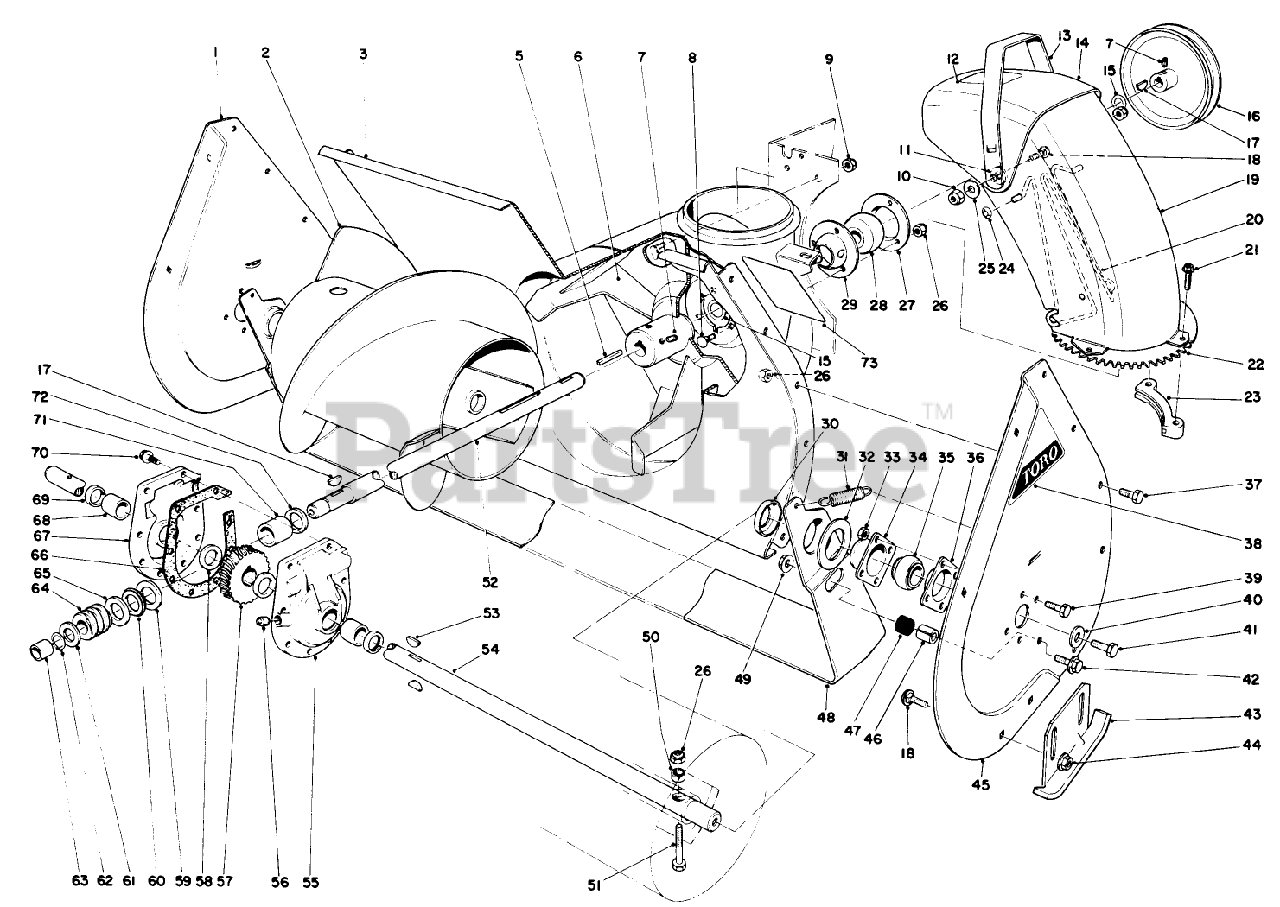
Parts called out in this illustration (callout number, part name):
1	RH AUGER SIDE PLT R
2	Auger Right
3	AUGER HSG WA RO
6	IMPELLER WA RO
7	SCREW-SET, SQH
8	BOLT-CARR
9	NUT-LOCK, NI
10	NUT-LOCK, CONE
11	WASHER-RUBBER
12	DECAL-DANGER DISCH.
13	DEFLECTOR HANDLE B
14	Deflector Chute (Incl. Ref. #12)
15	WASHER
16	IMPELLER PULLEY
17	KEY-WOODRUFF
18	SCREW-CARR
19	CHUTE B
20	CHUTE WIRE
21	SPECIAL SCREW
22	Gear-Chute Swivel
23	CHUTE RETAINER
24	NUT-PUSH
25	WASHER-BELLEVILLE
26	NUT-LOCK, NI
27	Bearing Flange Rear
28	BEARING-BALL
29	Bearing Flange Front
30	Positioner-Scraper
31	SPRING-TENSION
32	SCRAPER BLADE SPACER
33	NUT-LOCK, CONE
34	BEARING-FLANGE, FRONT
35	BEARING
36	BEARING-FLANGE, REAR
37	SCREW-HH
38	AUGER SIDE PLT DECAL
39	SCREW-HH
40	WASHER
41	SCREW-HH
42	SCREW-HHF
43	AUGER SKID WA R
44	NUT-HHF, WHIZ
45	LH AUGER SIDE PLT R
46	SCRAPER STOP SPACER
47	SCRAPER STOP CUSHION
48	24 SCRAPER BLD
49	NUT-HF
50	SPACER-HUB, AUGER
51	Auger Bolt
52	Shaft Impeller
53	KEY-WOODRUFF
54	24 AUGER SHAFT
55	Gear Case (Incl. Ref. #68 & 69)
56	PLUG-PIPE, SQH
57	GEAR-WORM, 27T
58	WASHER-THRUST
59	WASHER-THRUST
60	BEARING-THRUST
61	WASHER-THRUST
62	Ring-Snap
63	BUSHING
65	THRUST-WASHER
66	GASKET-CASE, GEAR
67	Gear Case (Incl. Ref. #68 & 69)
68	BUSHING
69	SEAL-OIL
70	SCREW-TAPTITE
71	BUSHING-SPECIAL
72	RING-QUAD
73	DECAL-WARNING, AUGER
